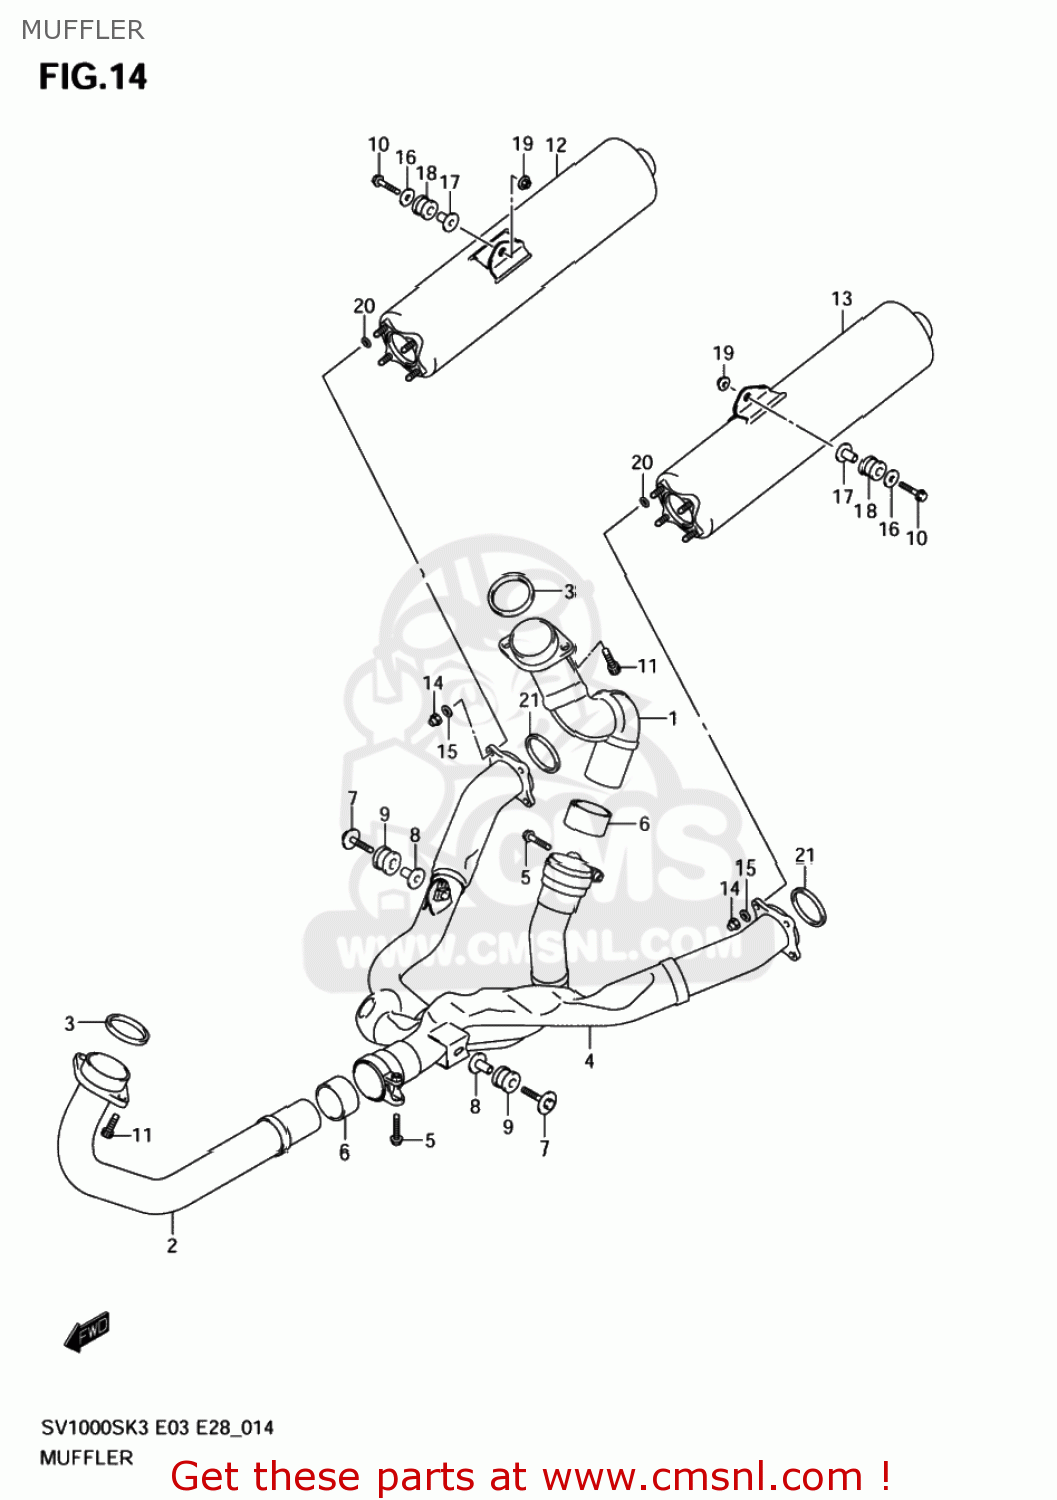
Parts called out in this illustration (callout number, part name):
1	PIPE,EXHAUST RR
2	PIPE,EXHAUST FR
3	GASKET,EXHAUST PIPE (NAS)
4	PIPE,EXHAUST CTR
5	BOLT(8X35)
6	CONNECTOR,MUFFLER
7	BOLT 8X45
8	SPACER(8.6X12X24.2)
9	CUSHION
10	BOLT(8X45)
11	BOLT(8X25)
12	BODY,MUFFLER,R
13	BODY,MUFFLER,L
14	NUT
15	WASHER(8.5X18X1.6)
16	WASHER(8.5X28X1.5)
17	SPACER(8.6X12X24.2)
18	CUSHION
19	NUT
20	O RING(D:1.9,ID:7.8)
21	GASKET,MUFFLER JOINT (NAS)
